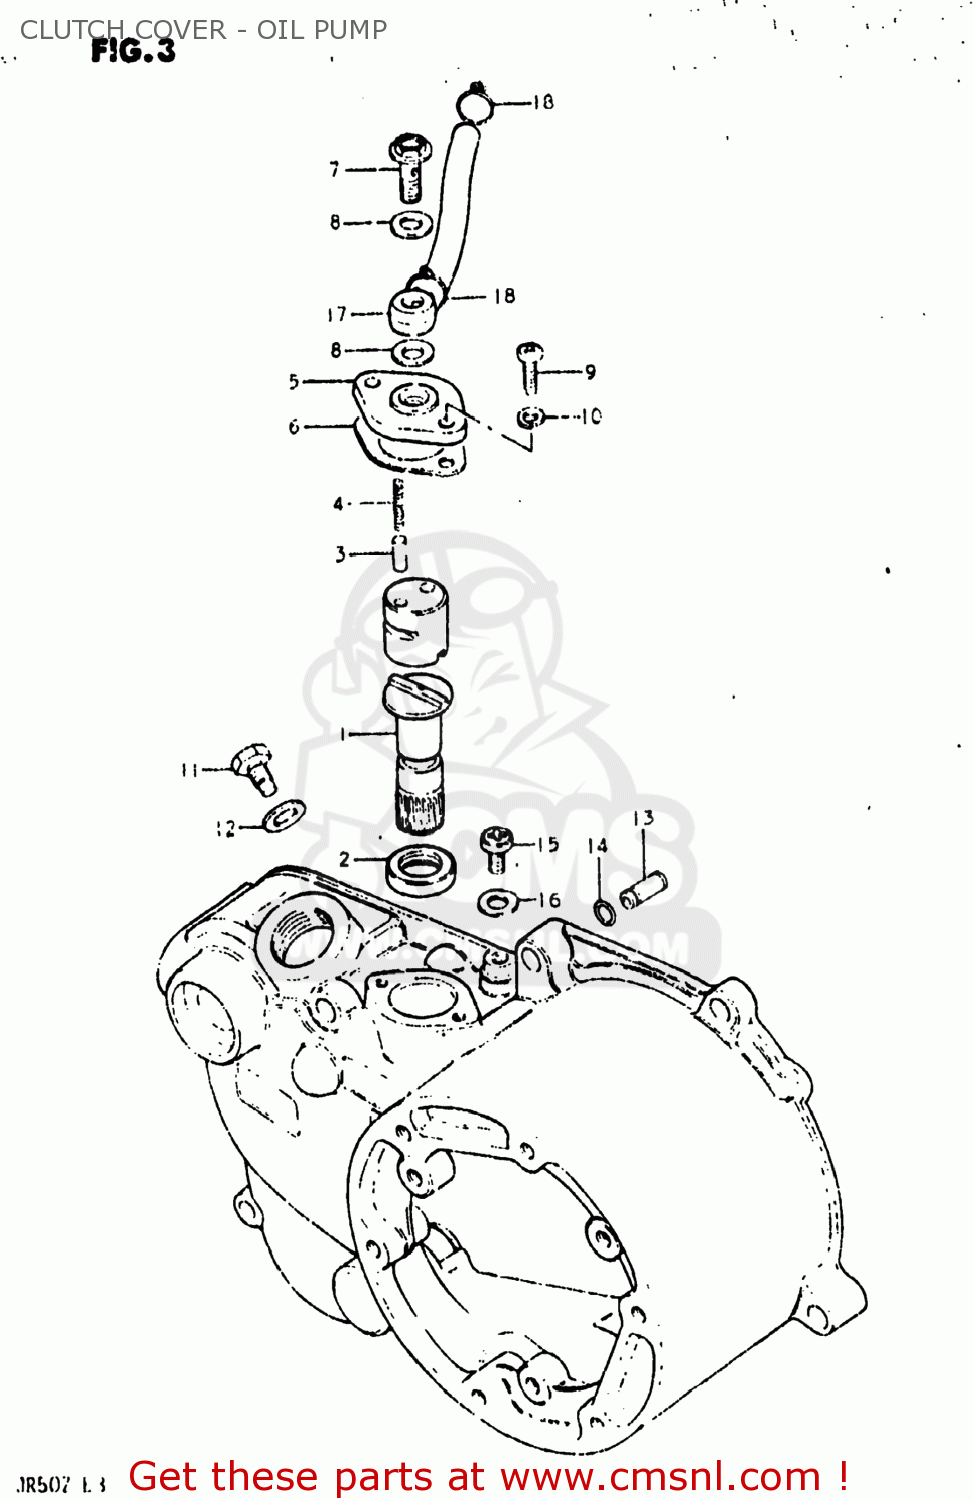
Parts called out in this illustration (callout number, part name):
1	GEAR,OIL PUMP DRIVE
2	SEAL,OIL(12X18.5X3)
3	PIN(2.3X7.5)
4	SPRING
5	CAM,OIL PUMP
6	GASKET,OIL PUMP (MCA)
7	UNION BOLT
8	GASKET(6.2X11X1).2 (NAS)
9	SCREW
10	LOCK WASHER
11	BOLT(6X10)
12	WASHER
13	VALVE,CRANK CHECK
14	O RING(D:1.05,ID:3.1)
15	SCREW
16	GASKET(5X9.5X1) (NAS)
17	HOSE,OIL NO.1
18	CLIP
